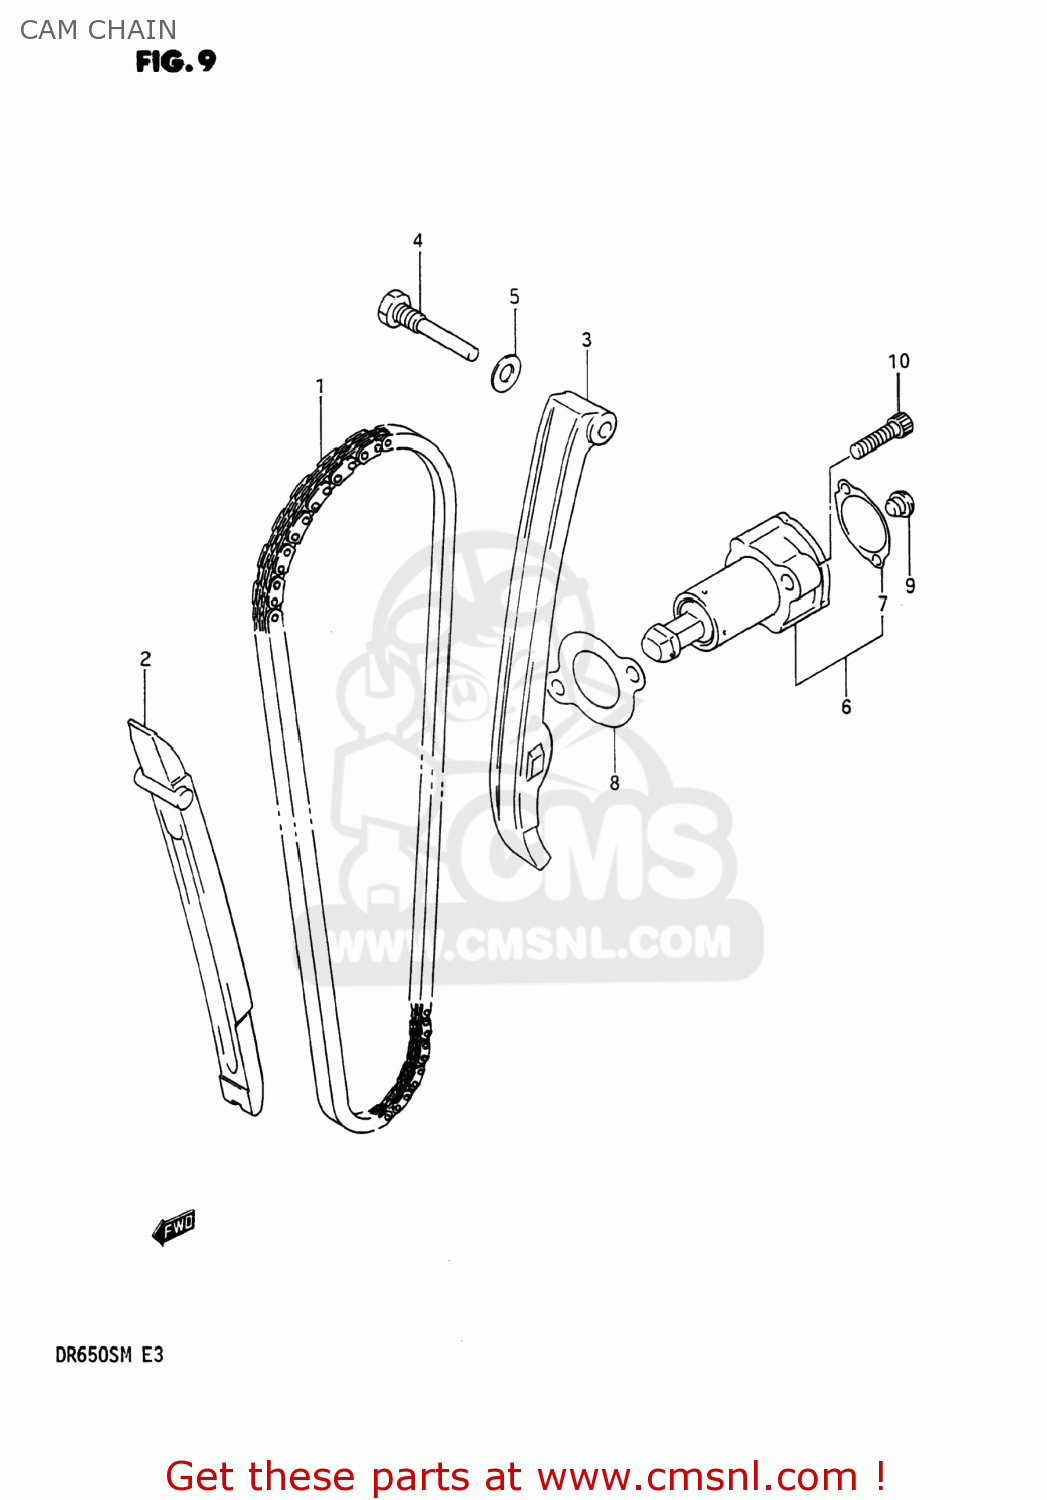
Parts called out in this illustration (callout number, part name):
1	CHAIN,CAMSHAFT DRIVE
2	GUIDE,CAM CHAIN
3	TENSIONER,CAM CHAIN
4	BOLT,CAM CHAIN TENSIONER
5	GASKET 8.2X14X1 (NAS)
6	ADJUSTER ASSEMBLY,TENSIONER
7	GASKET,ADJUSTER CAP (MCA)
8	GASKET,TENSIONER ADJUSTER
9	PLUG,ADJUSTER
10	BOLT
